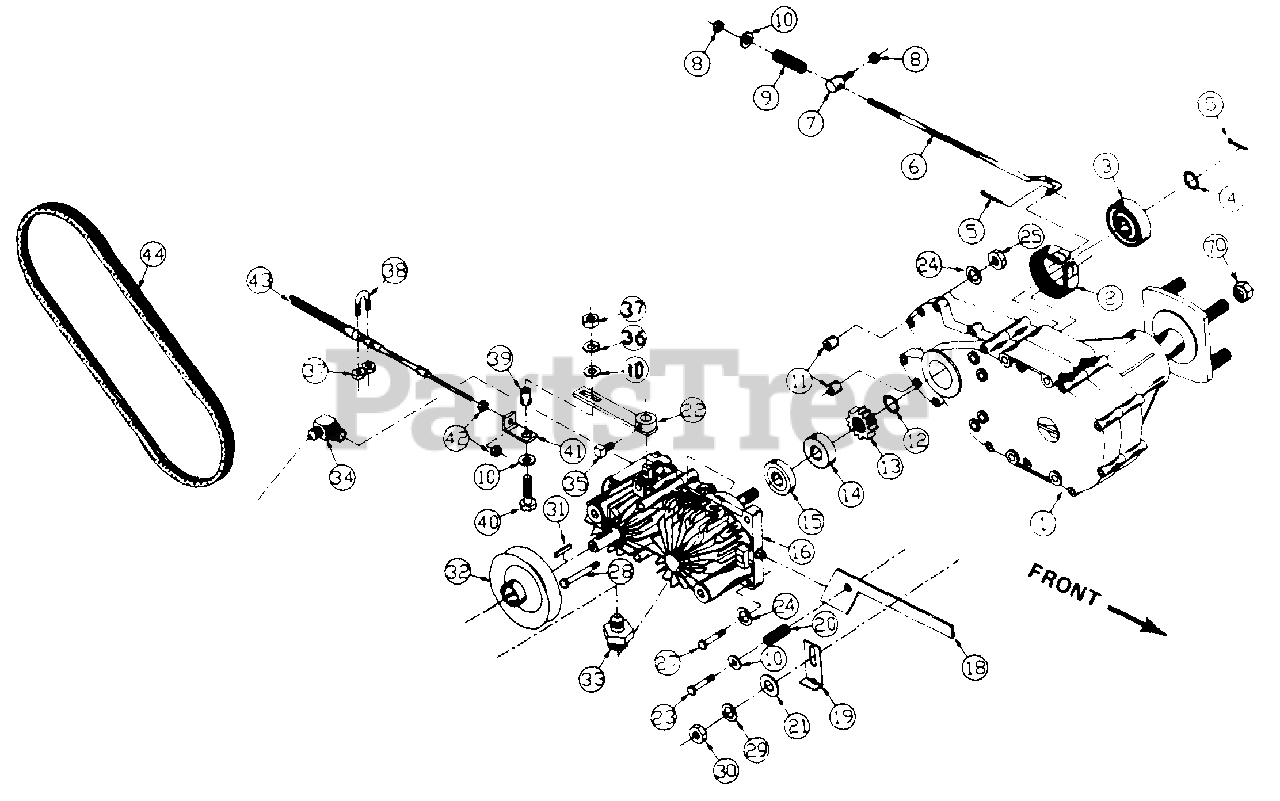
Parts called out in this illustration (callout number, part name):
1	ZT Transmission
5	Cotter Pin, 1/8" x 1"
6	Brake Linkage Rod
7	Caliper Rod Collar
8	Elastic Stop Nut, 1/4-20
10	Flatwasher, 1/4"
12	Snap Ring
14	Bearing
16	Sundstrand Pump, LH
18	Transmission Dump Lever
19	Transmission Dump Lever Stop
20	Compression Spring, 9/16" OD x 1 3/8"
21	Flatwasher, 3/8"
22	Transmission Arm
23	Dump Valve Bolt
24	Lockwasher, 5/16"
25	Hex Nut, 5/16-18
27	Hex Bolt, 5/16-18 x 2", GR5
28	Hex Bolt, 5/16-18 x 7 1/2", GR5
29	Lockwasher, 3/8"
30	Hex Nut, 3/8-16
31	Key, 5 x 5 x 25mm
32	Pulley, 4" OD x 15mm ID
33	Male Tube, Male O-ring Adapter
34	Male Tube, 90° Male O-ring Adpt.
35	Squarehead Setscrew, 5/16-18 x 1/2"
36	Lockwasher, 1/4"
37	Hex Nut, 1/4-20
38	Steering Cable Clamp
39	Steering Cable Bushing
40	Hex Bolt, 1/4-20 x 1", GR5
41	Steering Cable End
42	Hex Nut w/Star Washer, 10-32
43	Steering Cable, 3/16" x 58"
44	Pump Drive Belt
70	Lug Nut, 1/2-20
